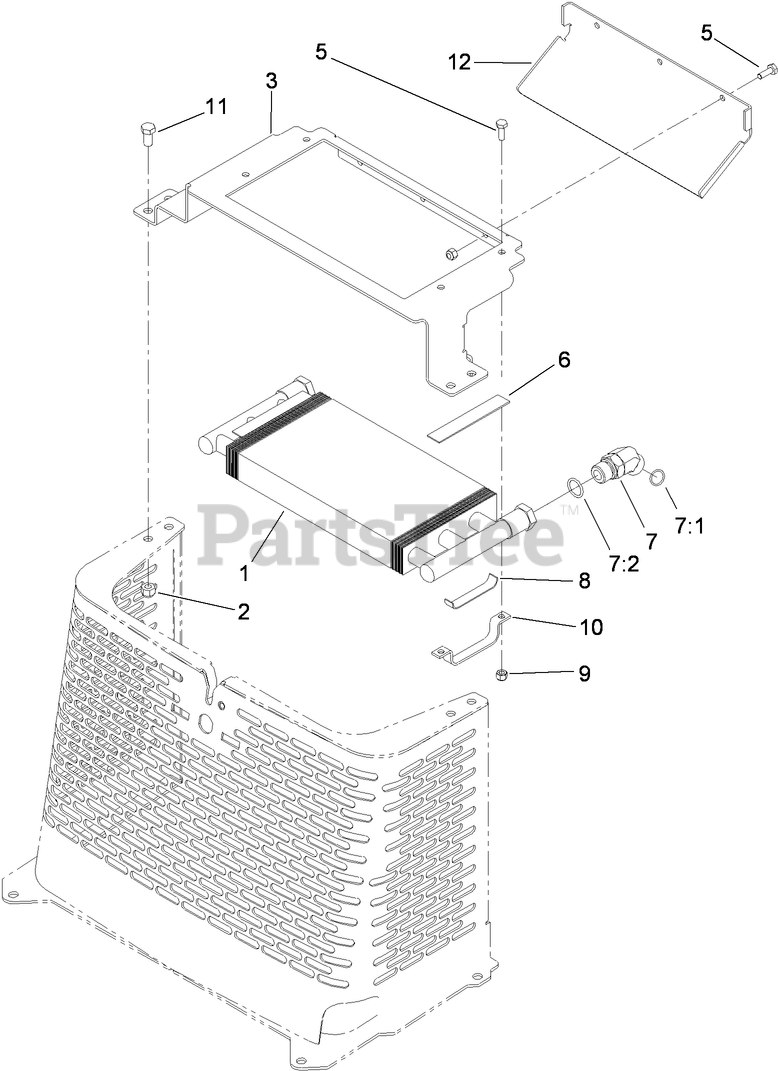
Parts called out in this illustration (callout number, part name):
1	EXCHANGER-HEAT
2	NUT-LOCK, NI
3	BRACKET-MOUNTING, COOLER
5	SCREW-HH
6	PAD-FOOTREST
7	FITTING-HYD-45
7:1	O-RING
7:2	O-RING
8	PAD-SUPPORT
9	NUT-LOCK, NI
10	SUPPORT-COOLER
11	SCREW-HHF
12	DEFLECTOR-COOLER
